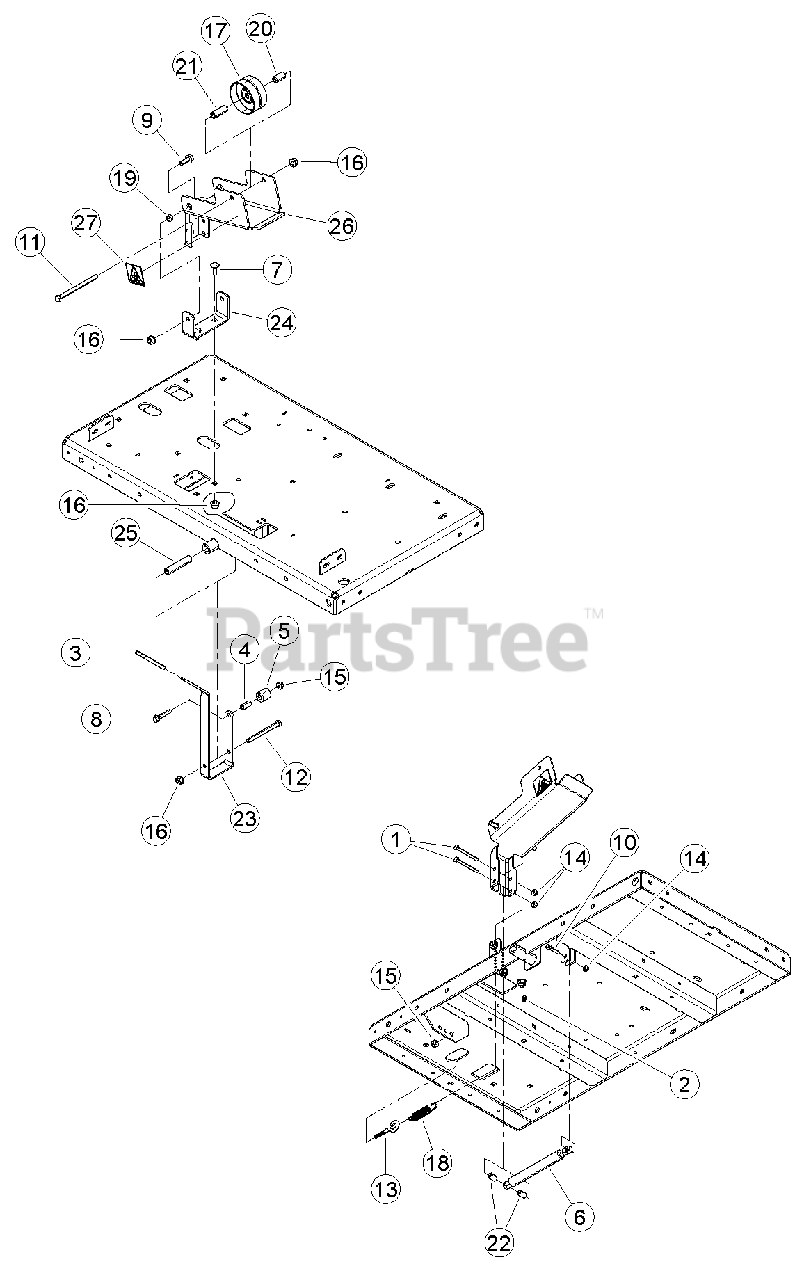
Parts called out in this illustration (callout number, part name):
1	BOLT, 1/4 X 2-3/4 HEX GR5 ZP
2	FITTING, 1/4 SELF-TAP GREASE
3	GRIP, CLUTCH HANDLE
4	SPACER, 0.5 X 1.00
5	ROLLER, 0.5 X 1.00 X 1.00 NYLON
6	DAMPER, IDLER
7	BOLT, 3/8 X 1 CRG GR5 NC ZP
8	BOLT, 5/16 X 1-3/4 FLANGE NC
9	BOLT, 3/8 X 1 FLANGE NC
10	BOLT, 1/4 X 1-1/4 FLANGE NC
11	BOLT, 3/8 X 5 HEX GR5 ZP
12	BOLT, 3/8 X 4 HEX GR5 NC ZP
13	I-BOLT, 5/16-18 X 2 ZP
14	NUT, 1/4-20 NYLOCK FLANGE
15	NUT, 5/16-18 NYLOCK FLANGE
16	NUT, 3/8-16 NYLOCK FLANGE
17	PULLEY, 3-1/4 FLAT IDLER
18	SPRING, 3/4"OD EXTENSION
19	SPACER, IDLER PIVOT
20	SPACER, IDLER
21	SPACER, .63 X 1.63
22	SPACER, .50 X .775
23	LEVER, CHIPPER ENGAGEMENT
24	ANCHOR, IDLER
25	SPACER, .63 X 3.060
26	BRACKET, IDLER SERVICE
27	DECAL, SHIELD DANGER ISO
